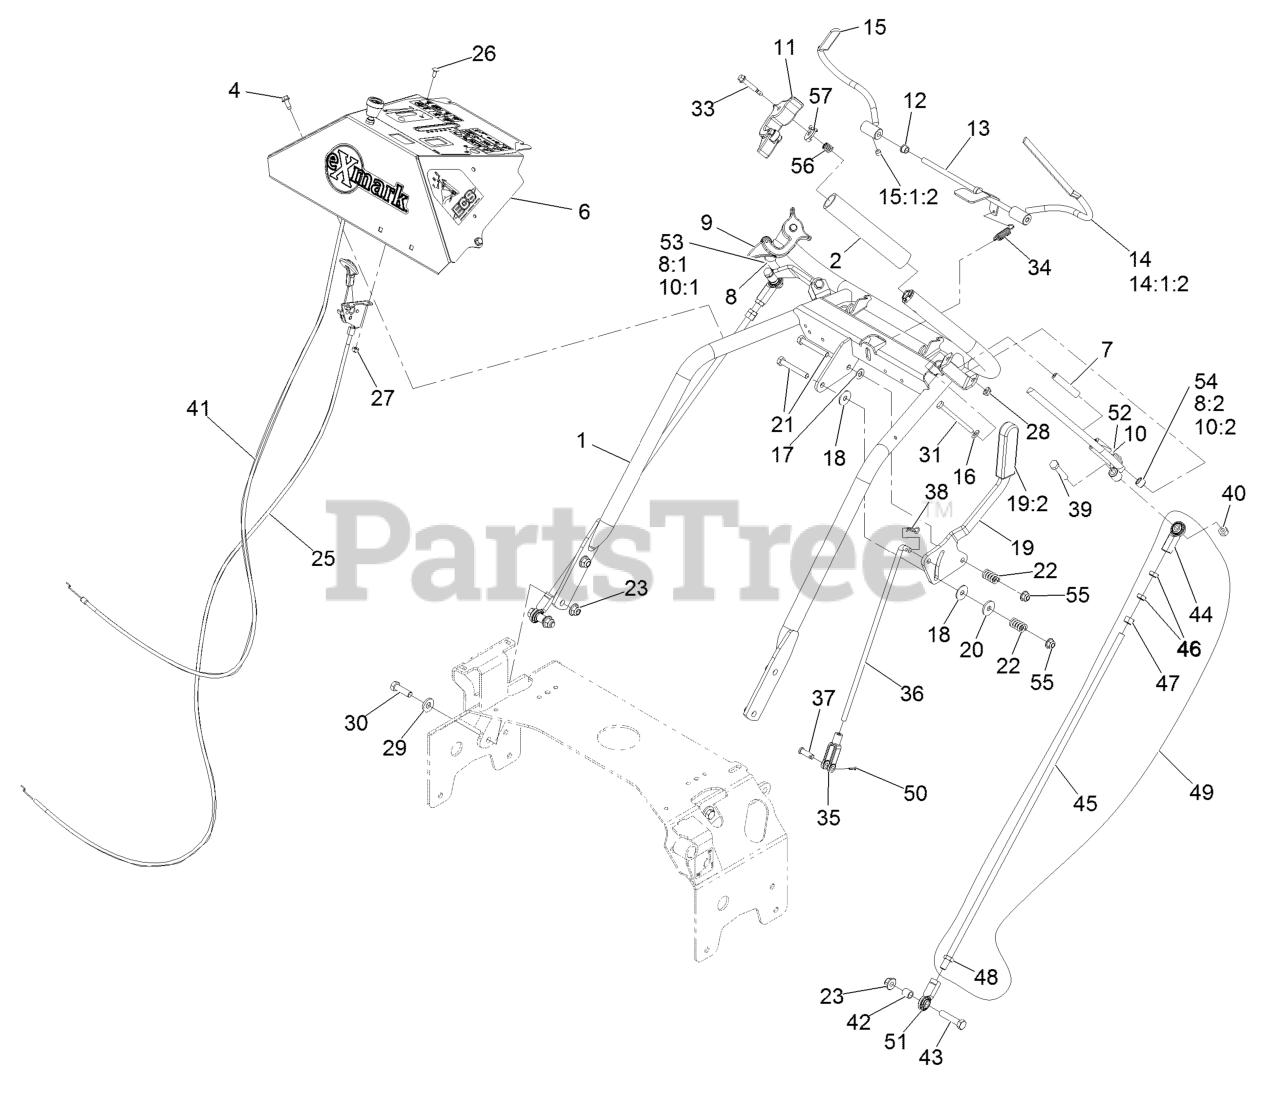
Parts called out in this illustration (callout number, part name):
1	WELD, HANDLE
2	GRIP-BAR, HANDLE
4	SCREW-HWH
6	ASM, CONSOLE W/ DECALS
7	BUSHING-LEVER, DRIVE
8	DRIVE LEVER-ASM, RH
8:1	WLD,RH DRIVE LEVER
8:2	BUSHING-SLEEVE
9	ASM,LATCH RH THUMB
10	DRIVE LEVER-ASM, LH
10:1	WLD,LH DRIVE LEVER
10:2	BUSHING-SLEEVE
11	ASM,LATCH LH THUMB
12	BUSHING-NYLON
13	WLD,OPC LEVER AXLE
14	WLD,LH OPC LEVER
14:1:2	SCREW-SET
15	WLD,RH OPC LEVER
15:1:2	SCREW-SET
16	WASHER-FLAT
17	WASHER-PLAIN
18	WASHER-FRICTION
19	LEVER, SHIFT W/GRIP
19:2	GRIP-HANDLE, STEERING
20	WASHER-FRICTION
21	SCREW-HH
22	SPRING-COMPRESSION
23	NUT-HF, NI
25	CONTROL-THROTTLE
26	BOLT-CARR
27	NUT-LOCK, NI
29	WASHER-BELLEVILLE
30	SCREW-HH
31	SCREW-HH
33	SCREW-SHOULDER
34	SPRING-EXTENSION
35	YOKE-ADJUSTABLE
36	ROD,SPEED CONTROL
37	PIN-CLEVIS
38	PIN-COTTER
39	SCREW-HH
40	NUT-LOCK, NI
41	CABLE, CHOKE
42	SPACER-TUBE, PUMP LINK
43	SCREW-HH
44	JOINT-BALL, END
45	LINK,DRIVE (PLTD)
46	NUT-HJ
47	NUT-HEX
48	NUT-HEX JAM, LH
49	DRIVE LINK ASM
50	PIN-COTTER
51	JOINT-BALL END, LH
52	WLD,LH DRIVE LEVER
53	WLD,RH DRIVE LEVER
54	BUSHING-SLEEVE
55	NUT-HF, NI
56	SPRING-TANK, FUEL
57	LATCH, ECS
